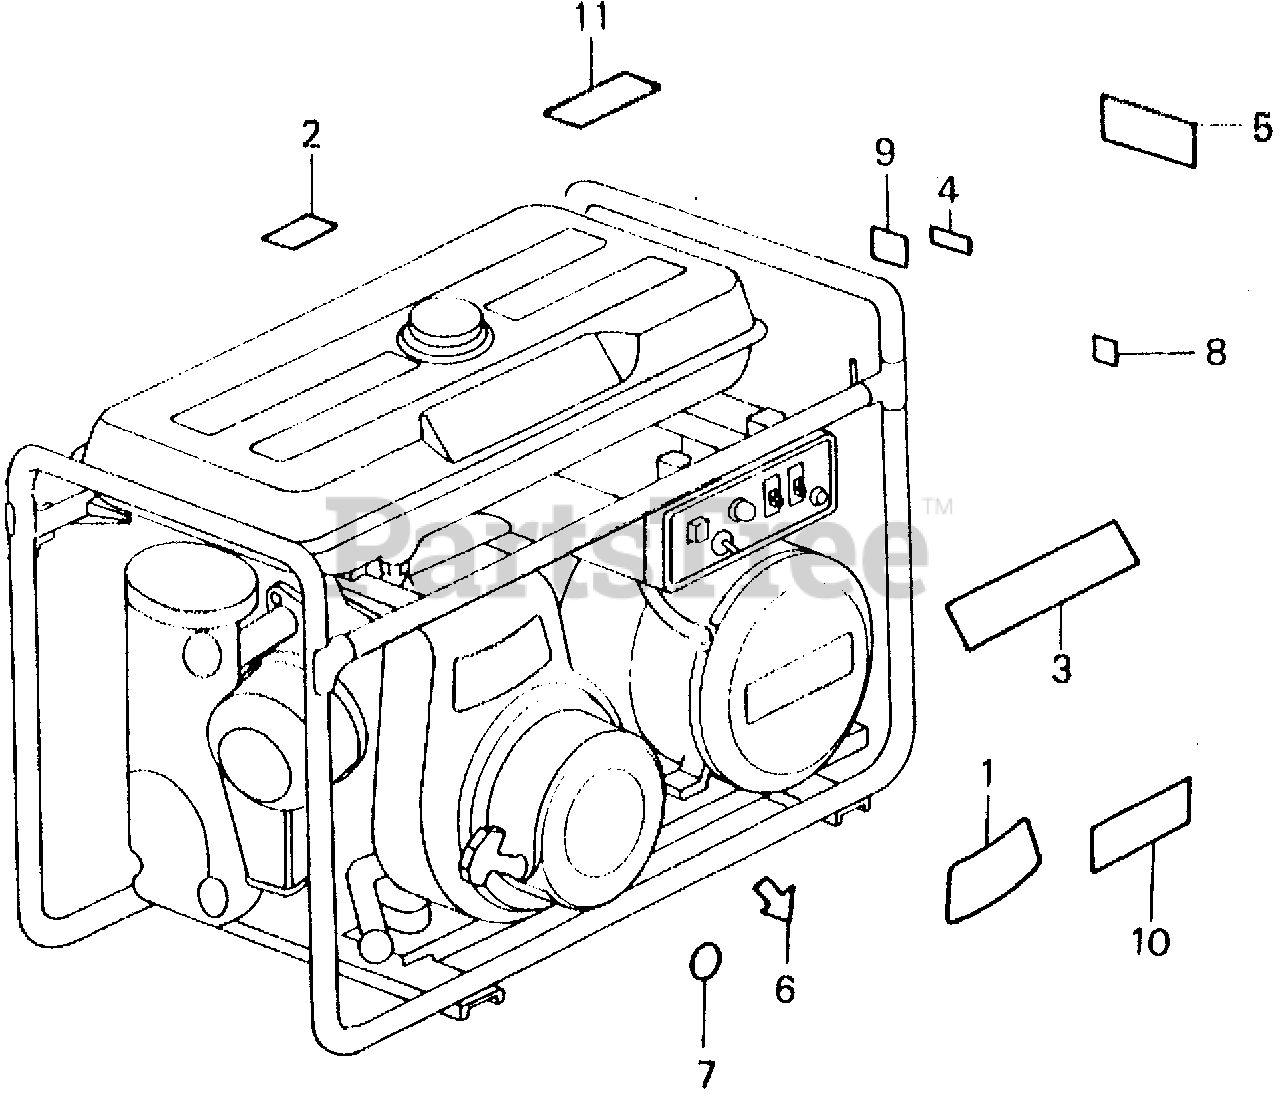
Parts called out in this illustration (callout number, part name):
1	EMBLEM
1	PLATE, CAUTION (NOT AVAILABLE)
2	MARK A, CAUTION
3	MARK, TOP (NOT AVAILABLE)
3	PLATE, CAUTION (NOT AVAILABLE)
4	MARK, CAUTION
5	MARK, OUTPUT
6	MARK, CHOKE
7	MARK, KNOB (NOT AVAILABLE)
8	MARK, GROUND
9	MARK B, D.C. OUTPUT
10	MARK, PLATE
11	MARK, CAUTION (CO)(ENGLISH/FRENCH)(SPANISH)
